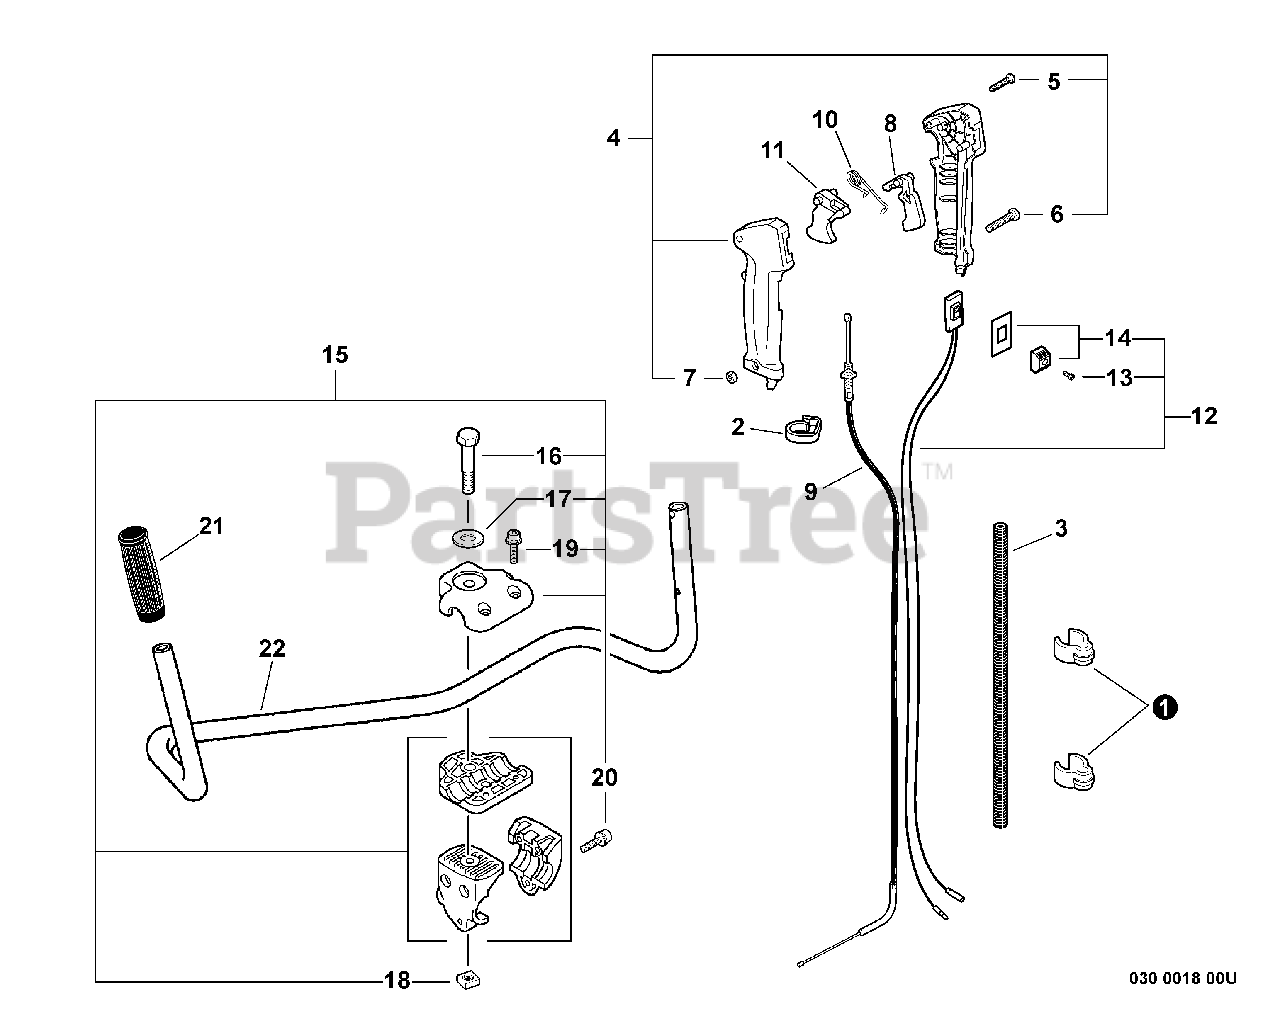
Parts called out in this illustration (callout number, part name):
3	TUBE, PROTECTIVE - CORRUGATED
4	THROTTLE CONTROL ASSY
5	SCREW - 3X25
6	SCREW - 5X30
8	LOCKOUT, THROTTLE
9	CABLE, THROTTLE
10	SPRING, LOCKOUT LEVER
11	TRIGGER, THROTTLE
12	IGNITION SWITCH ASSY
13	SCREW - 3X10
14	KNOB, SWITCH - ORANGE
15	HANDLE BRACKET KIT
16	BOLT - 8X55
17	WASHER - 8
19	SCREW - 5X20
20	SCREW - 5X30
21	GRIP, HANDLE - LEFT
22	HANDLE - FRONT
